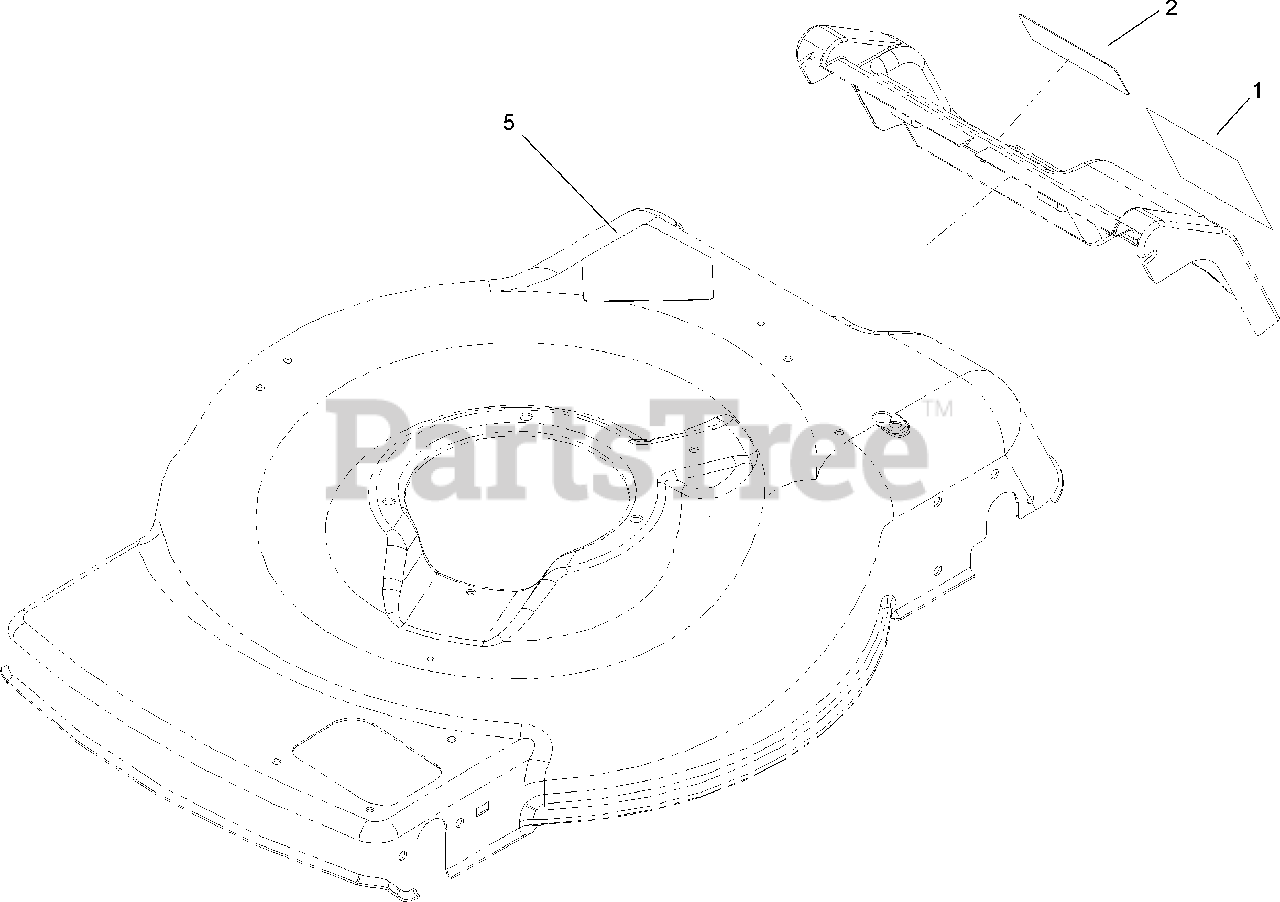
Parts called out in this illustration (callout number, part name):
1	DECAL-WARNING
2	DECAL-WARNING
5	DECAL-DANGER
